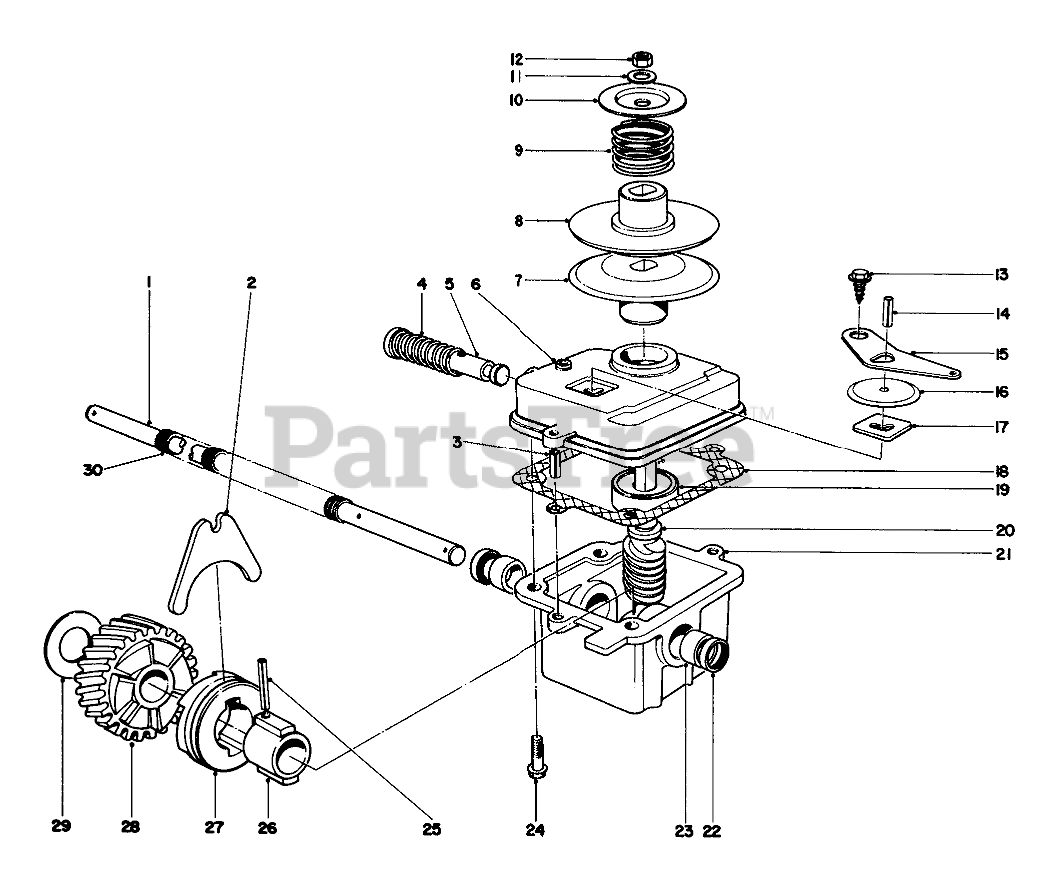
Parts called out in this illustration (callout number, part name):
1	Drive Shaft
2	SHIFTER FORK
3	3/16 X 1/2 ROLL PIN
4	SPRING
5	Shift Rod
6	GEAR CASE COVER
7	LOWER PULLEY HALF
8	Pulley Half Upper
9	COMPRESSION SPRING
10	SPRING RETAINER
11	WASHER-FLAT
12	NUT-HEX, SIDE DEFORM
13	Screw
14	PIN-ROLL
15	SHIFTER ARM
16	TRANS DUST COVER
17	LATCH PLATE
18	GASKET
19	Bearing
20	Shaft-Worm
21	Gear Case (Incl. Ref. #22 & 23)
22	Seal
23	Bushing
24	Screw
25	COIL PIN
26	SLEEVE
27	CLUTCH JAW
29	THRUST WASHER
30	DRIVE SHAFT COVER
